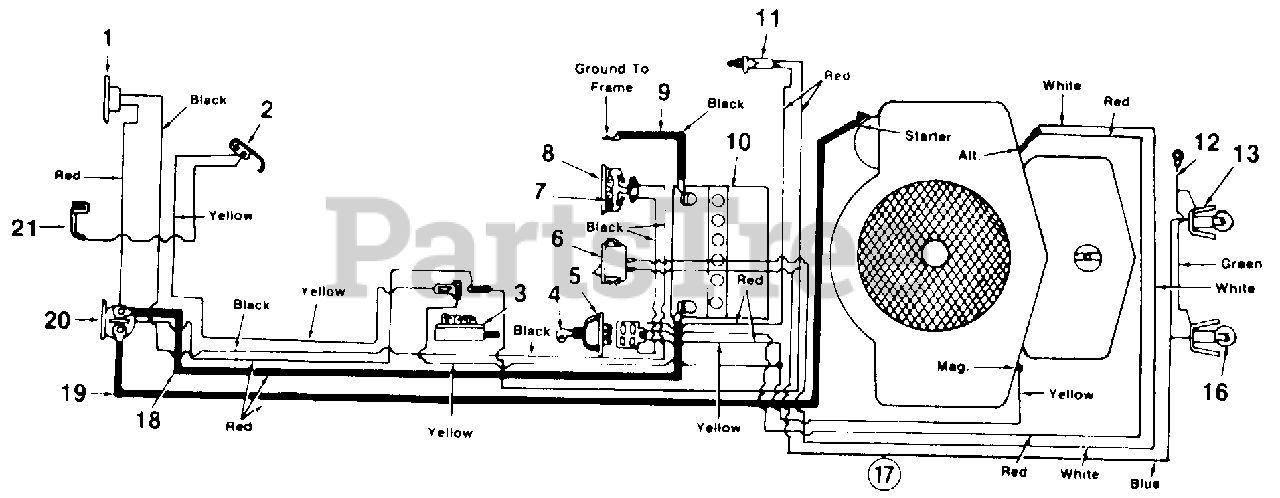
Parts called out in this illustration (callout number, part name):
1	Circuit Breaker
2	Spring Switch
3	Safety Switch Dpst.
5	Ignition Switch
6	Headlight Switch
8	Ammeter
9	Ground Wire 14.0" Lg.
10	12 Volt Battery
11	Safety Switch
13	Socket
16	Lamp
18	Electric Wire 27.0" Lg.
19	Electric Wire 32.5" Lg.
20	Solenoid
21	Spring Switch
